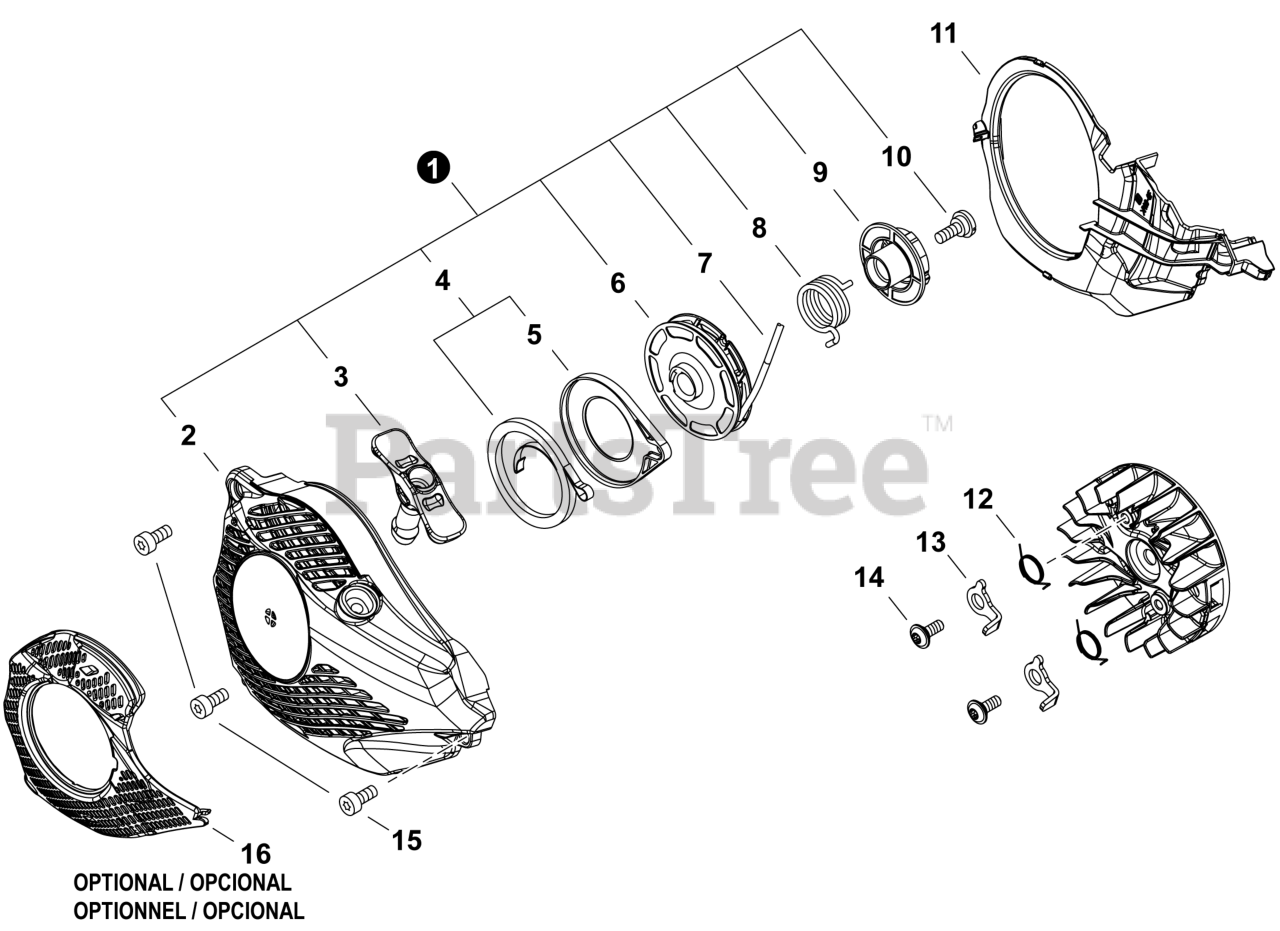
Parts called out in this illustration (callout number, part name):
1	STARTER ASSY
2	CASE ASSY, STARTER
3	GRIP, STARTER
4	SPRING KIT, REWIND
5	SPRING CASE
7	ROPE, STARTER 3x700
8	SPRING, RETURN
9	PLATE, CAM
10	SCREW 5
11	COVER, FAN
12	SPRING, TORSION
14	BOLT 5x11
15	BOLT, TORX 4x16
16	SHIELD, DEBRIS
